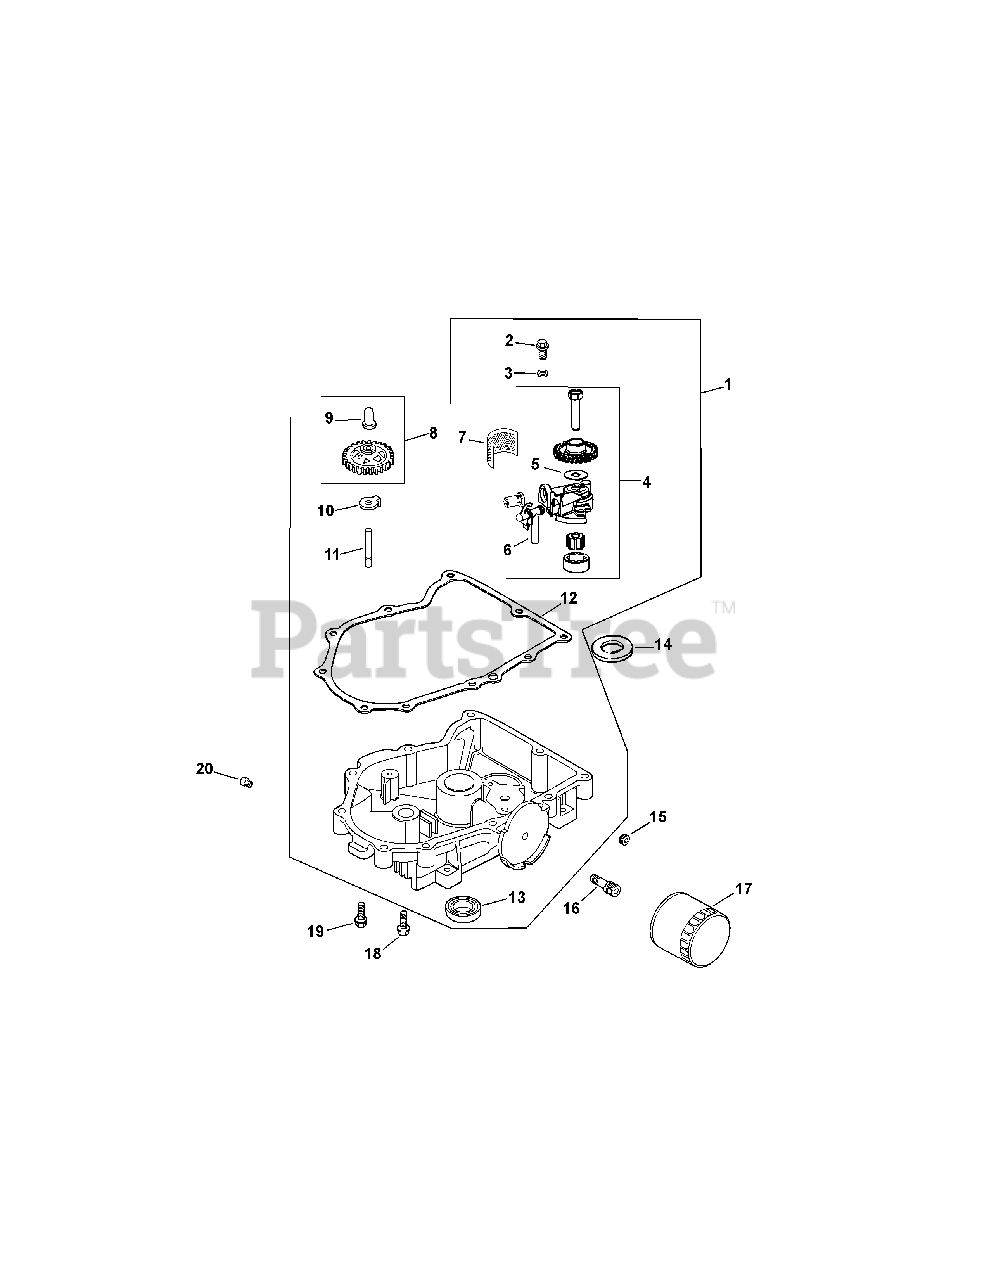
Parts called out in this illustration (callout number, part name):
1	KIT, OIL PAN ASSEMBLY (Includes 2-10)
2	SCREW
4	KIT, OIL PUMP ASSEMBLY (Includes 5,6)
6	TUBE, OIL PICK-UP (CV)
8	KIT, GOVERNOR GEAR W/PIN (Includes 9)
12	GASKET, OIL PAN
16	NIPPLE, OIL FILTER
18	SCREW, HEX FLANGE
19	SCREW, HEX F! LANGE
